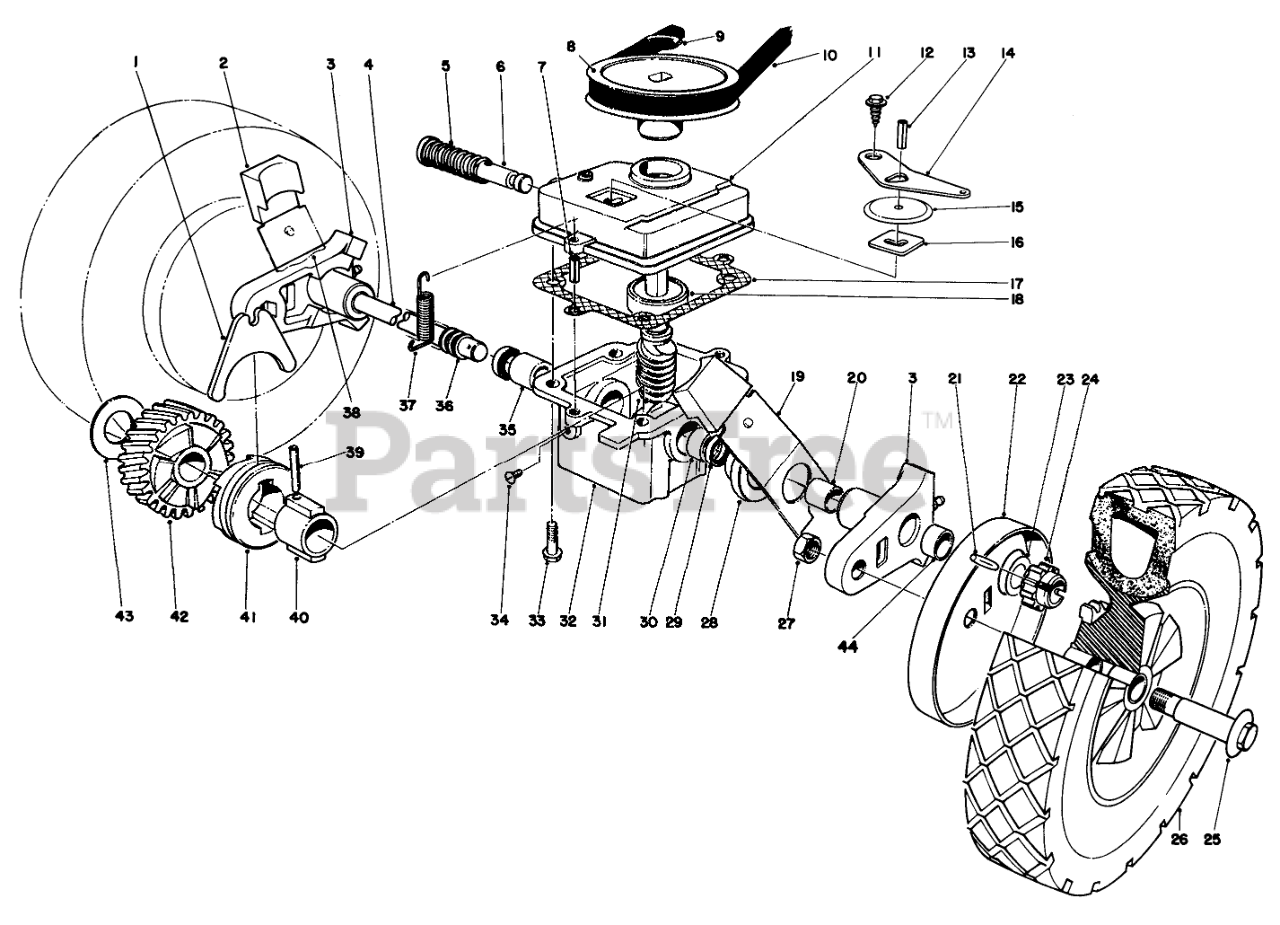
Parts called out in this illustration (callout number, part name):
1	SHIFTER FORK
2	KNOB-ARM
3	Pivot Arm (Incl. Ref. #20 & 40)
4	DRIVE SHAFT (SERVCE)
5	SPRING
6	Shift Rod
7	3/16 X 1/2 ROLL PIN
8	PULLEY
9	PUSH-ON 93-3236
10	V BELT
11	Cover Gear Case
12	Screw
13	PIN-ROLL
14	SHIFTER ARM
15	TRANS DUST COVER
16	LATCH PLATE
17	GASKET
18	Bearing
19	SPRING ARM ASM SP LH
20	BUSHING
21	Pin
22	WHEEL COVER
23	WASHER-THRUST
24	Pinion
25	BOLT-WHEEL
26	Wheel & Tire Assembly
27	Nut
28	End Cap
29	Seal
30	Bushing
31	Worm Shaft & Gear (Incl. Ref. #42)
32	Gear Case (Incl. Ref. #29-30 & 35)
33	Screw
34	NYLON SCREW
35	Bushing
36	COVER-SHAFT, DRIVE
37	TENSION SPRING
38	SPRING ARM ASM SP RH
39	COIL PIN
40	SLEEVE
41	CLUTCH JAW
42	Helical Gear
43	THRUST WASHER
44	BUSHING
